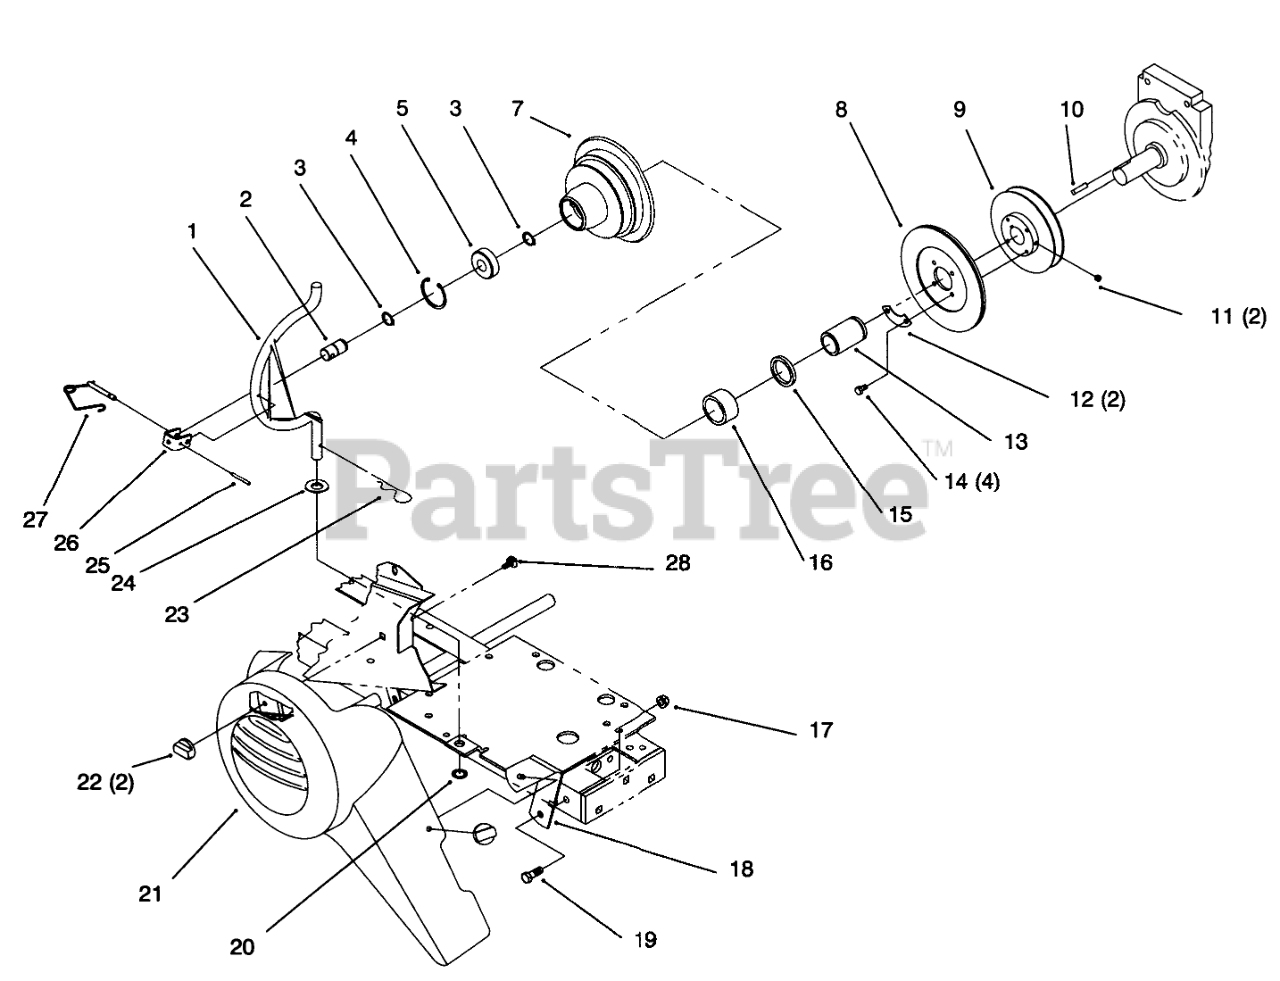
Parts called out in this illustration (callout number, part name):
1	ROD-HOUSING
2	SHAFT-PTO
3	Ring-Snap
4	RING-RETAINING
5	BEARING-BALL
7	Housing-Clutch
8	Facing-Clutch
8	ASS'Y-CLUTCH PLATE
9	PULLEY
11	SCREW-SET, HSH
12	RETAINER
13	RACE-BEARING
14	SCREW-HEX HD CAP
15	SEAL-OIL
16	Seal
17	NUT-FLANGE
18	Bracket
19	SCREW-HH
20	RING-REINFORCED CIRC
21	GUARD - BELT
22	NUT - WING
23	PIN-COTTER, HAIR
24	WASHER-FLAT
26	CLEVIS
27	LOCKING PIN ASM
28	Retainer-Bolt
